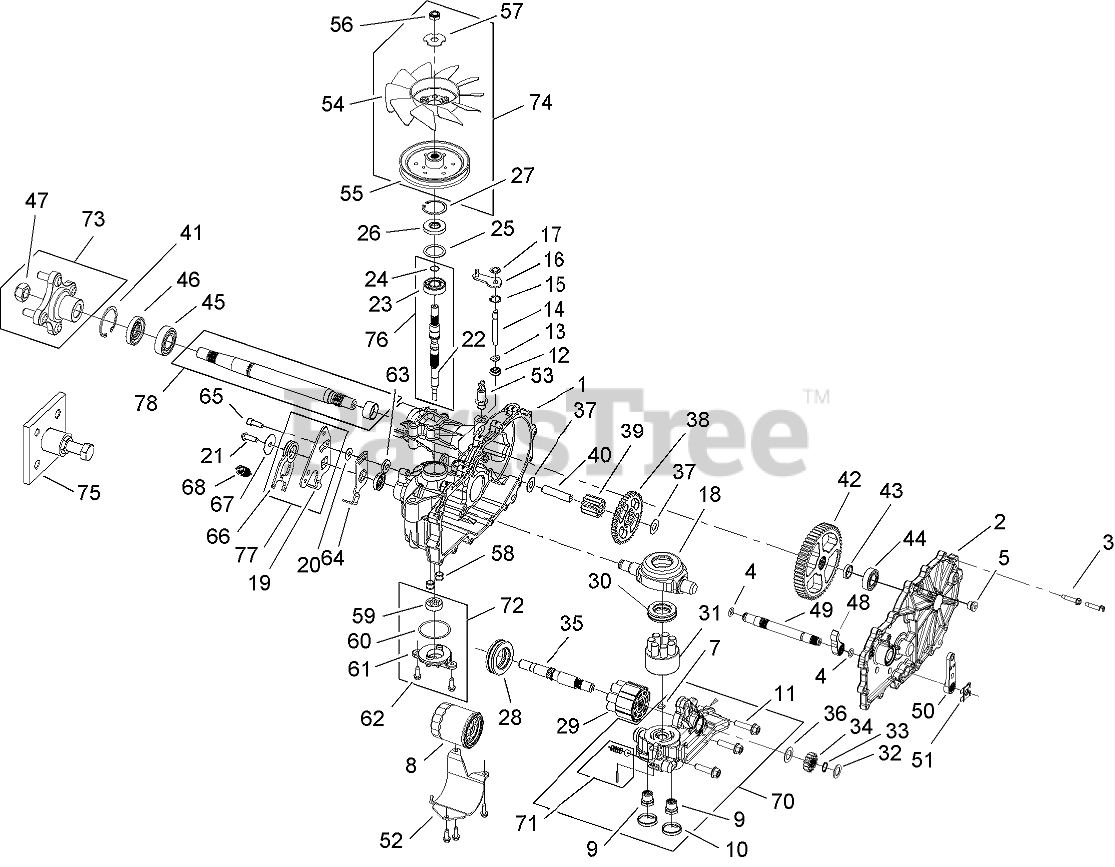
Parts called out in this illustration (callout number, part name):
1	MAIN HOUSING KIT
2	RH SIDE COVER KIT
3	SCREW-HHF
4	O-RING
5	PLUG
7	PLATE-BYPASS
8	ELEMENT-OIL FILTER, HYD
9	CHECK PLUG
10	SEAL-PLUG
11	SCREW-HFHC
12	SEAL-LIP
13	RING-RETAINING, EXTERNAL
14	ROD-BYPASS
15	RING-RETAINING, INTERNAL
16	ARM-BYPASS
17	RING-RETAINING, EXTERNAL
18	SWASHPLATE-TRUNNION
19	ARM-CONTROL, RH
20	WASHER
22	SHAFT-INPUT
23	BEARING-SHAFT, INPUT
24	RING-RETAINING
25	SPACER
26	SEAL-LIP
27	RING-RETAINING
28	BEARING-THRUST
29	MOTOR CYLINDER BLOCK KIT
30	BEARING-THRUST
31	PUMP BLOCK ASM
32	WASHER-FLAT
33	RING-RETAINING
34	GEAR-14T
35	SHAFT-MOTOR
36	WASHER
37	WASHER
38	GEAR-45T
39	GEAR-11T
40	PIN-JACKSHAFT
41	RING-RETAINING
42	GEAR-54T
43	SPACER
44	BEARING-BALL
45	BEARING-BALL
48	PAWL-BRAKE
49	SHAFT-BRAKE, INBOARD
50	HANDLE-BRAKE
51	CLIP-RETAINING
52	GUARD-FILTER, RH
53	ADAPTER-STRAIGHT
54	FAN-7.0
55	PULLEY-5.0 INCH
56	NUT-LOCK
57	WASHER-SLOTTED
58	TUBE-CONNECTING
59	GEROTOR ASM
60	O RING-SEAL
61	COVER-CHARGE PUMP
63	SPACER
64	ARM-NEUTRAL, RIGHT
65	Screw-Sh
66	CW RTN ASM
67	WASHER
68	SPRING-EXTENSION
70	RH CENTER SECTION KIT
71	CHARGE RELIEF KIT
72	CHARGE KIT
73	HUB KIT
73:2	HUB W/STUDS
74	FAN AND PULLEY KIT
74:2	Pulley
74:3	LOCKNUT,HEX
74:4	Washer
75	PULLER-HUB, 4 BOLT
76	INPUT SHAFT KIT
77	RTN CW KIT
78	AXLE SHAFT KIT
